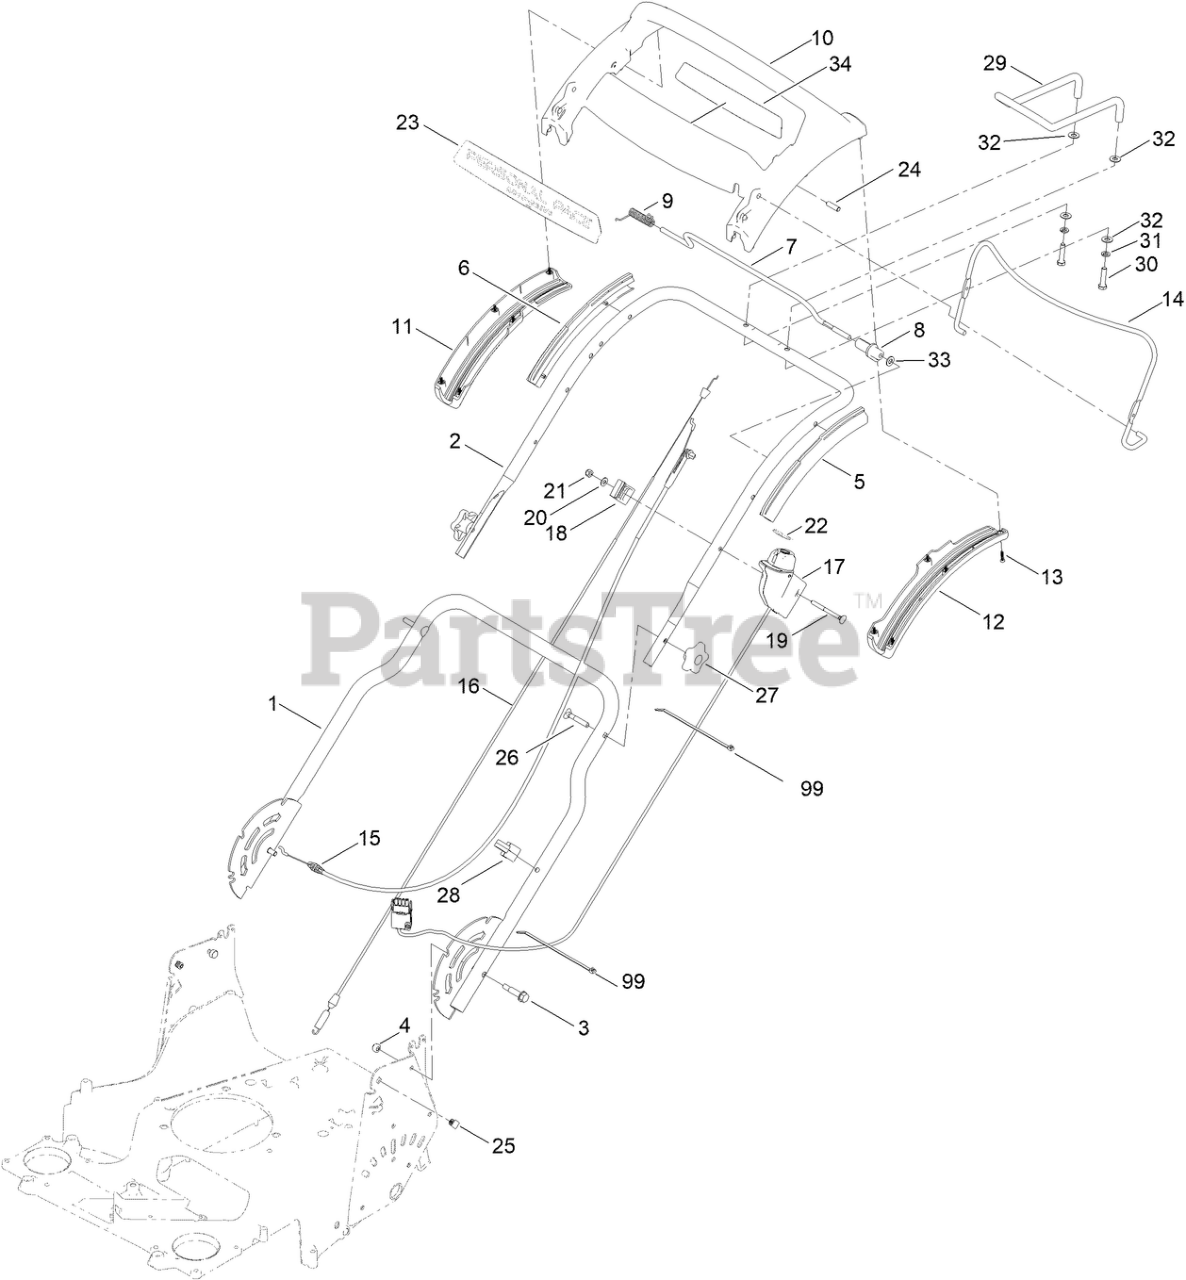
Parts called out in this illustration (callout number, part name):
1	HANDLE-LOWER, ASM
2	HANDLE-UPPER
3	BOLT-SHOULDER, HHF
4	NUT-HEX
5	GUIDE-CURVED, LH (RWD)
6	GUIDE-CURVED, RH (RWD)
7	ROD-CONTROL, TRACTION
8	LEVER-TRACTION, RWD
9	SPRING-TORSION
10	HANDLE-PERSONAL PACE, CURVED
11	BOTTOM-HANDLE, RH
12	BOTTOM-HANDLE, LH
13	SCREW-PPH
14	BAIL-BRAKE
15	CABLE-BRAKE, PP BS
16	CABLE-TRACTION
17	STARTER SWITCH ASM
18	CLAMP-CABLE
19	SCREW-HANDLE
20	WASHER-FLAT
21	NUT-HEX
22	DECAL-CONTROLS
23	DECAL-HANDLE, PP
24	PIN-HANDLE, PP
25	PLUG-SQUARE
26	SCREW-HANDLE
27	KNOB-HANDLE
28	GUIDE-CABLE
29	HANDLE-ASSIST, STEEL
30	SCREW-HH
31	WASHER-LOCK
32	WASHER
33	WASHER-PLAIN
34	DECAL-CONTROLS (60V, START)
99	TIE-CABLE
